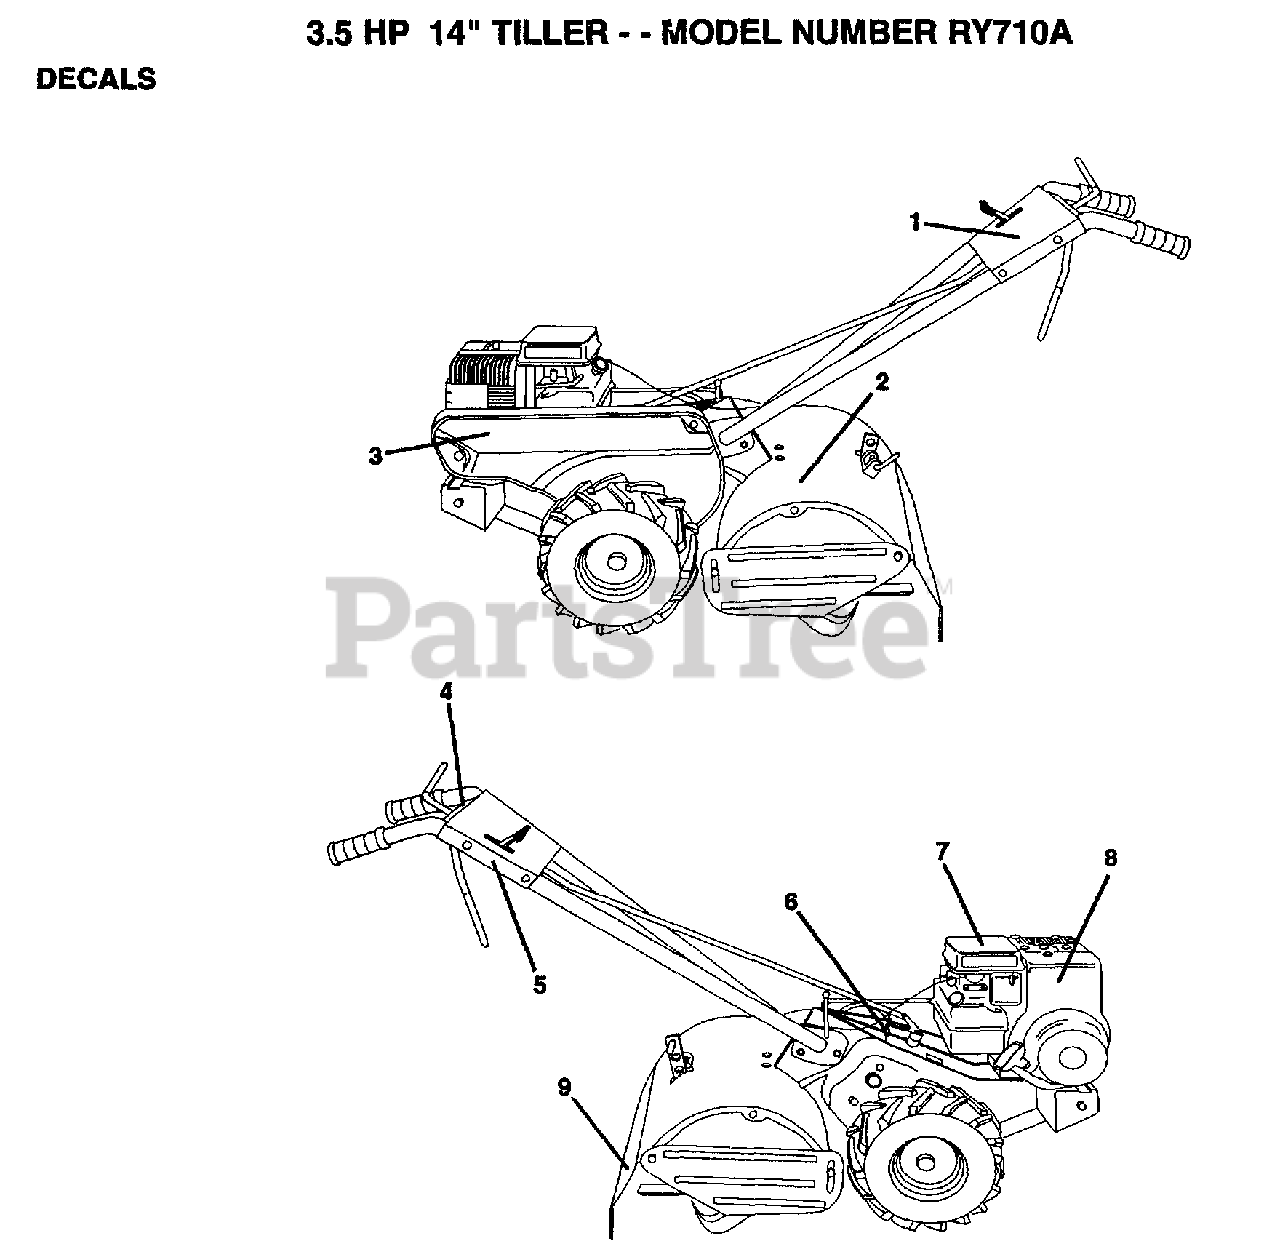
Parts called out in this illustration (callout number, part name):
5	DECAL TI
7	DECAL TI
8	"DECAL,ENG HP"
